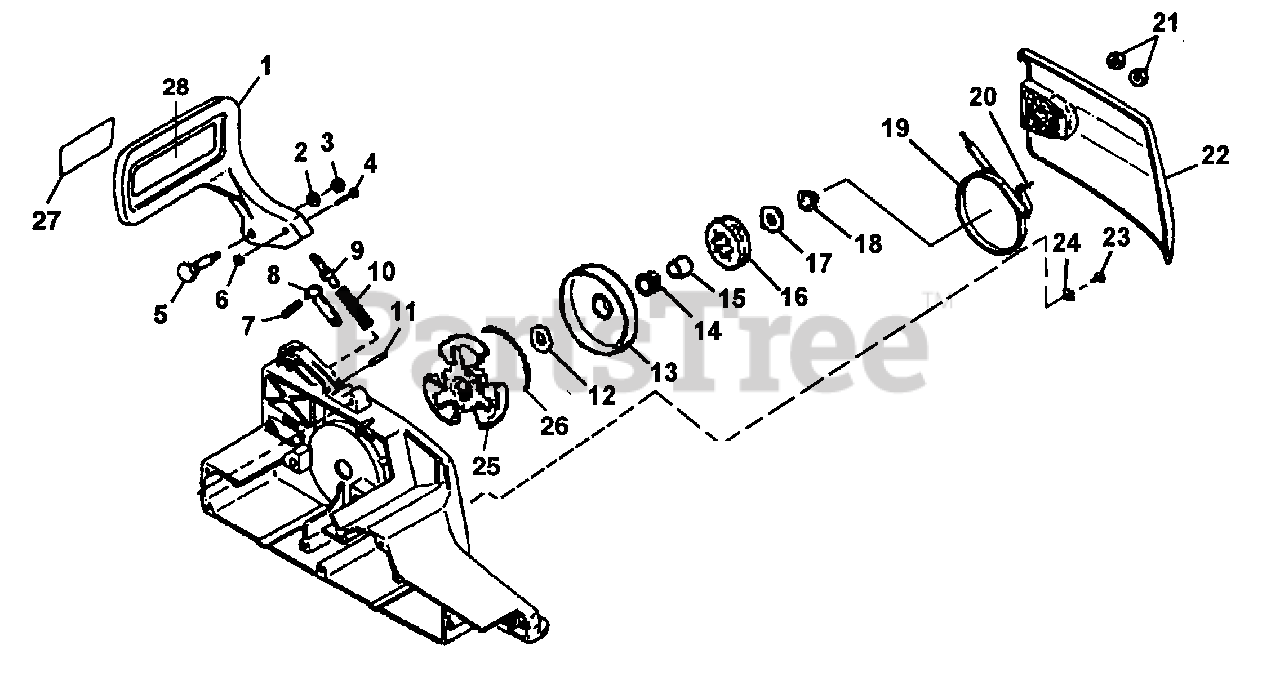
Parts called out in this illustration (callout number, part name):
1	GUARD, HAND
2	WASHER, BELLVILLE
3	NUT - (M5)
5	SCREW, SHOULDER
6	RING, RETAINER
7	SPRING, COIL
8	BRAKE LATCH ASSY.
9	ADJUSTER, BRAKE
10	SPRING, COMPRESSION
12	WASHER, THRUST (INNER)
13	SPLINE & DRUM
14	BEARING, NEEDLE
15	RACE, INNER
16	SPROCKET, RIM (.325 X 77)
17	WASHER, THRUST
18	NUT, HEX LOCK (3/8"-24)
19	BRAKE BAND ASSY
20	PIN, DOWEL
21	NUT, HEX
22	DRIVE CASE COVER CASE
23	SCREW, THREAD FORM (#6)
24	RETAINER, BRAKE BAND
25	CLUTCH ASSY
26	SPRING, CLUTCH
27	LABEL, KICKBACK
28	DECAL, SAFETY
